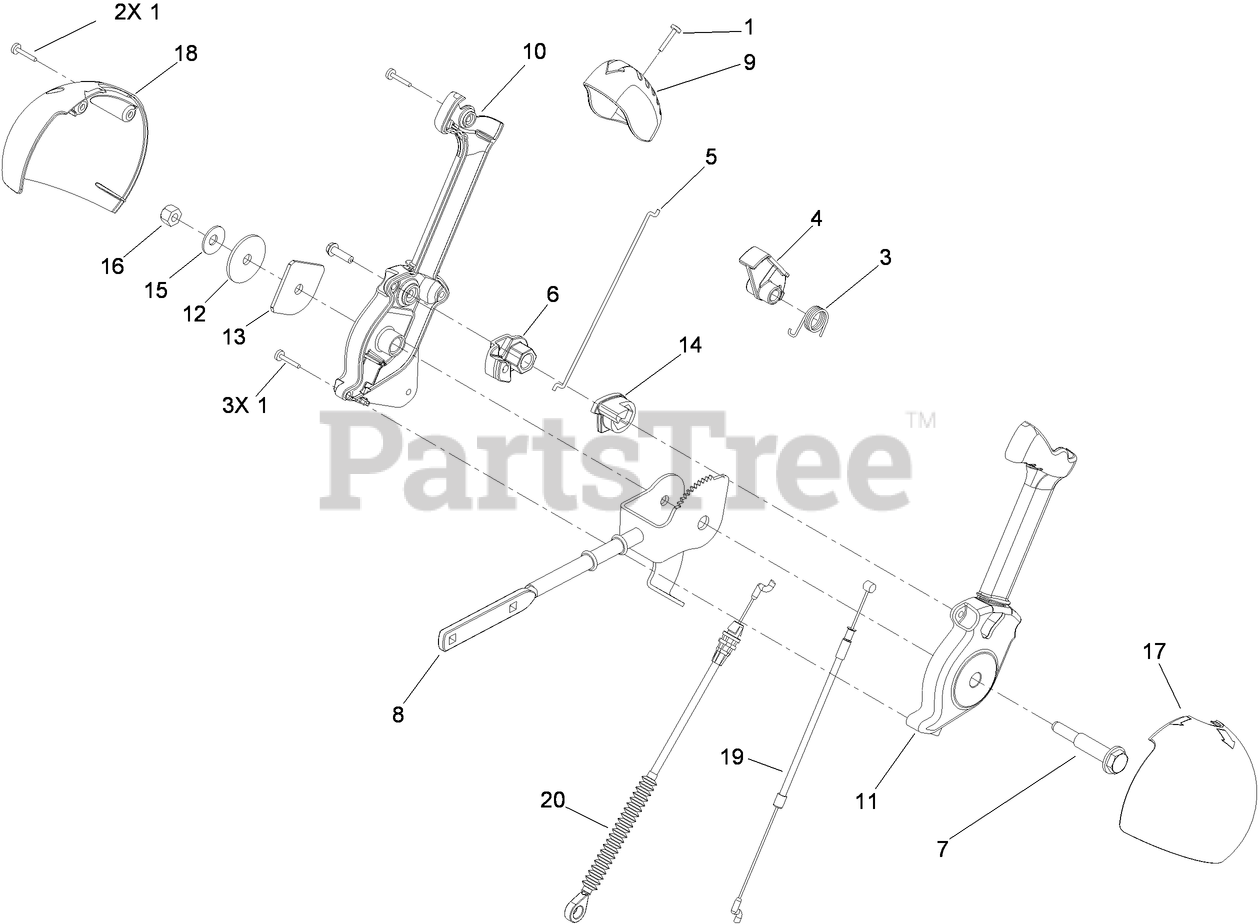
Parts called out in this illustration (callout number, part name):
1	SCREW-PPH
3	SPRING-TORSION
4	TRIGGER-LATCH
5	LINK-LATCH
6	LEVER-CABLE, DEFLECTOR
7	SCREW-SHOULDER
8	ROD-CONTROL, CHUTE
9	CAP-LEVER
10	LEVER-CONTROL, CHUTE (RH)
11	LEVER-CONTROL, CHUTE (LH)
12	WASHER-NYLON
13	PLATE-FRICTION
14	PAWL-LATCH
15	WASHER-BELLEVILLE
16	NUT-LOCK, NI
17	COVER-LEVER, CHUTE (LH)
18	COVER-LEVER, CHUTE (RH)
19	CABLE-RELEASE, CHUTE
20	CABLE-CONTROL, DEFLECTOR
